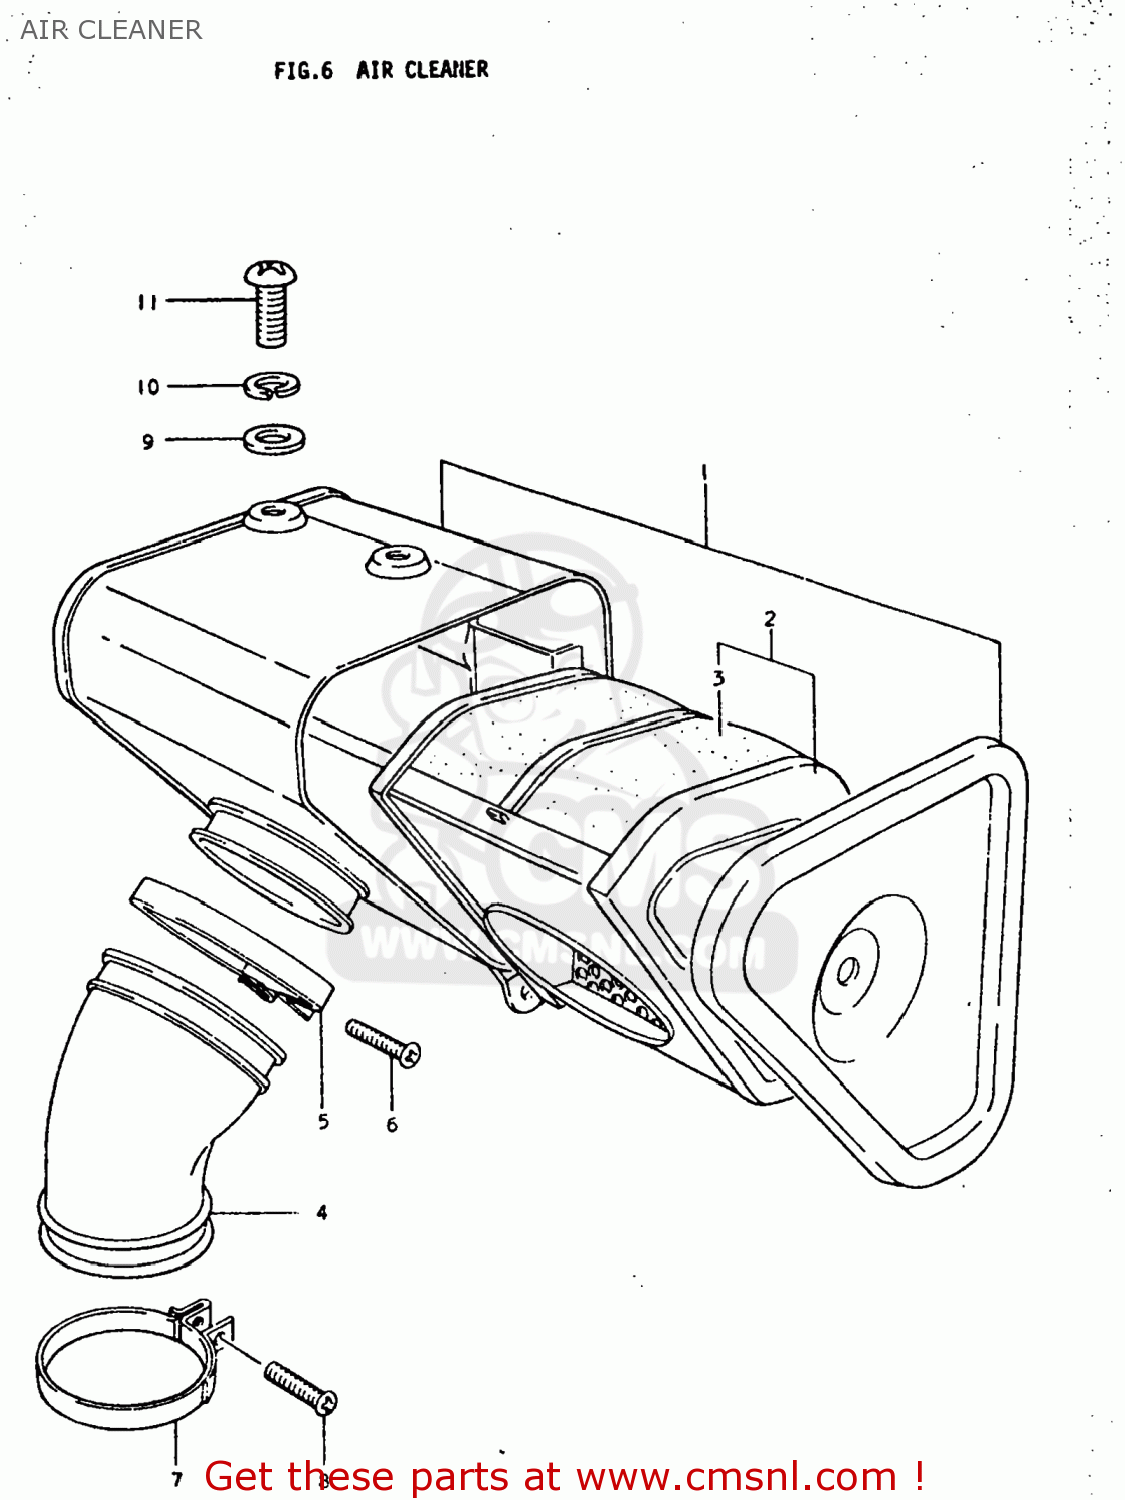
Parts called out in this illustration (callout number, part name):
1	CLEANER ASSEMBLY,AIR
2	FILTER,AIR CLEANER
3	FILTER
4	HOSE,CARBURETOR AIR INLET
5	CLAMP
6	SCREW
7	CLAMP
8	SCREW
9	WASHER
10	LOCK WASHER
11	SCREW 6X12
